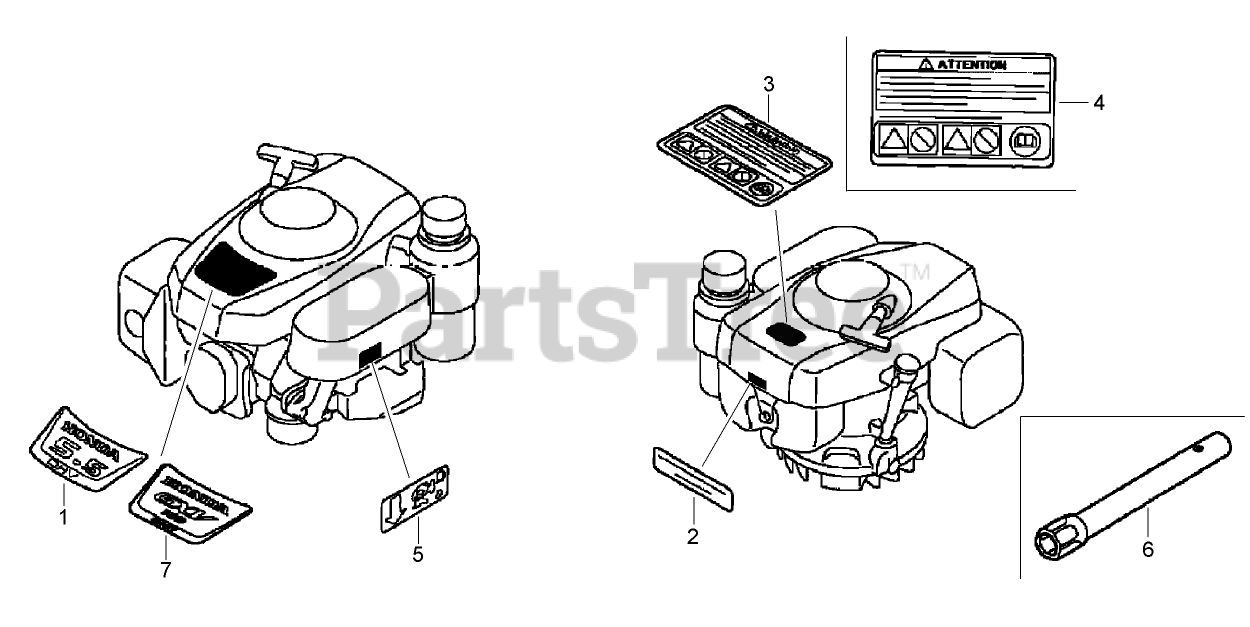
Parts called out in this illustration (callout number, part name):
1	MARK, EMBLEM (SERIAL NUMBERS UP TO 1036455)
2	MARK-MANUFACTURER
3	MARK-CAUTION, OPERATOR (ENGLISH)
3	MARK-CAUTION, OPERATOR (FRENCH)
4	MARK-CAUTION, OPERATOR (PICTOGRAPH)
5	MARK-CAUTION, FUEL PETCOCK
6	Wrench-Box (P21)
7	MARK, EMBLEM (GXV160) (SERIAL NUMBERS FROM 1036456)
